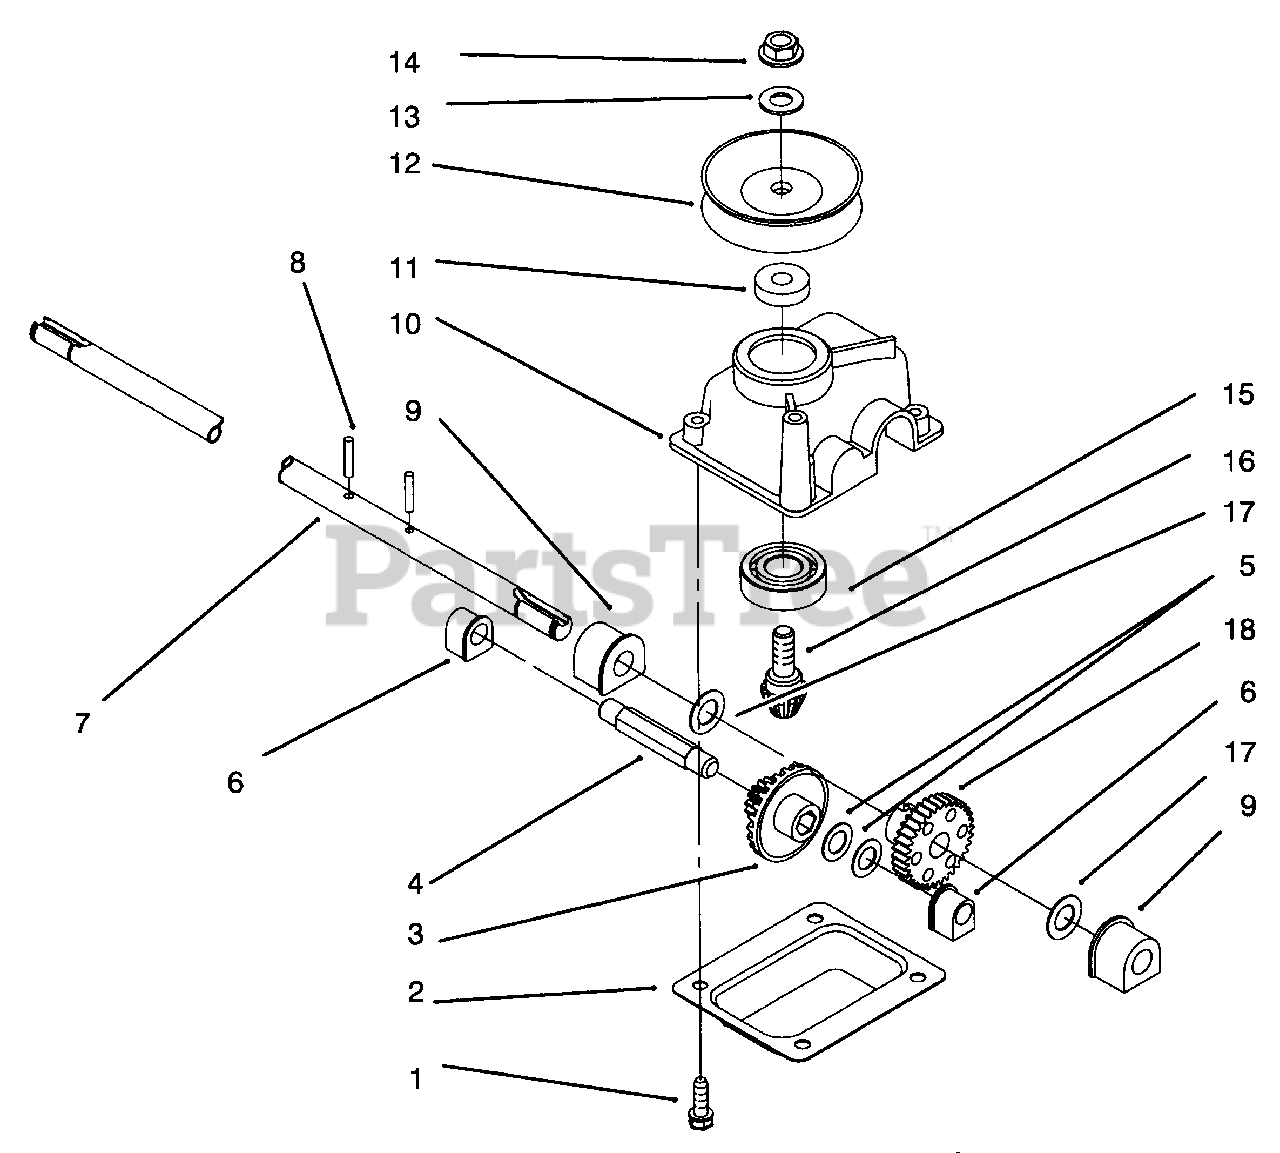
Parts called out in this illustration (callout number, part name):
1	Screw-Taptite
2	Cover-Gear Case
3	Pinion-15 Tooth
4	Shaft-Intermediate
7	Shaft-Output
8	Pin-Groove
9	Bushing-Output
10	Gearcase
12	Pulley-Half
15	Bearing-Ball
16	Gear-Bevel Pinion
17	Washer-Thrust
18	Gear 34 Tooth
